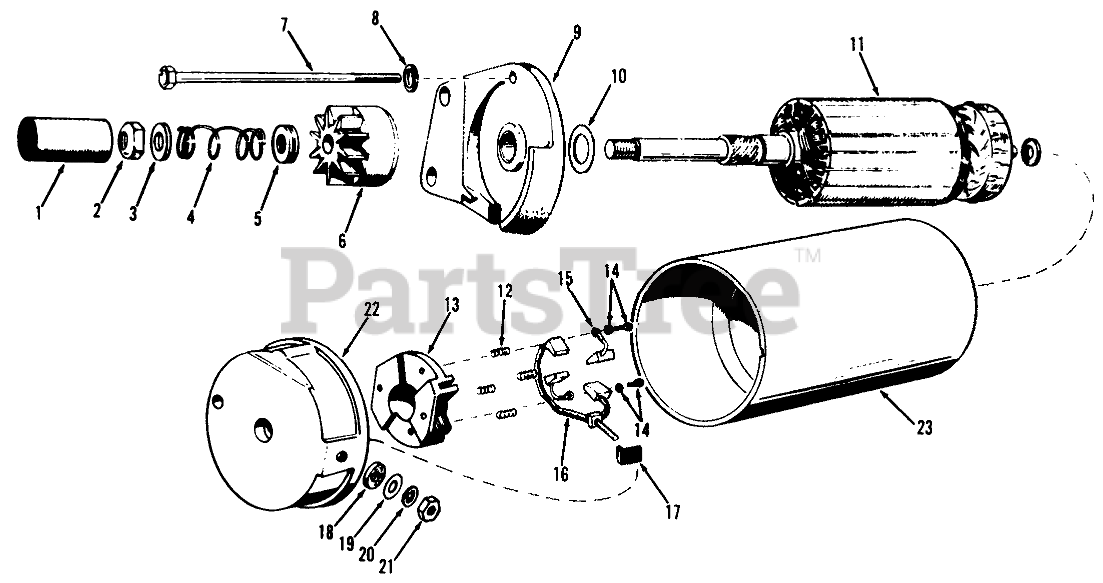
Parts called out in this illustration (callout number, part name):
1	Dust Cover
2	Stop Nut
3	Washer-Stop Nut
4	Spring-Anti Drift
5	Dust Cover Spacer
6	Drive Assembly
7	Tie Bolt
8	Lock Washer
9	Cap Assy-Drive End
10	Armature Thrust Washer
11	Armature
22	Cap Assy-Inc Parts 12-21
23	Repair Kit Inc 12, 15 & 16
